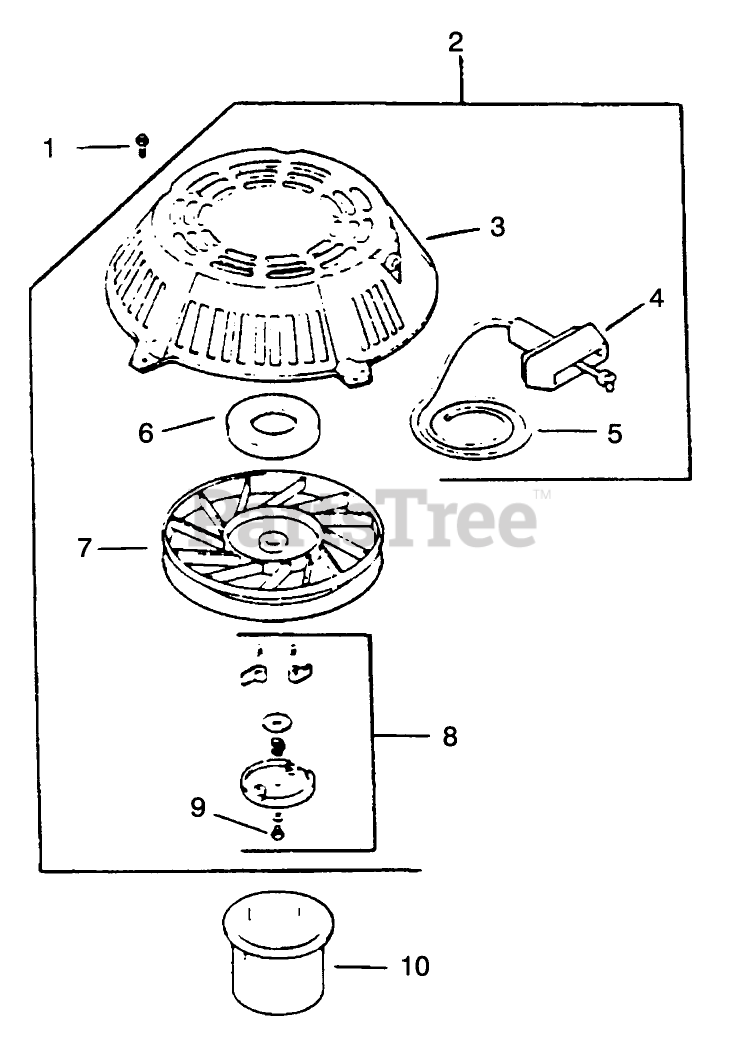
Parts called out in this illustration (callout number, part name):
2	Starter (Incl.Ref.#3-9)
3	Housing-Starter
4	Handle
5	Rope
6	Spring Keeper
7	Pullet
8	Kit-Dog Replacement
10	Cup-Drive
